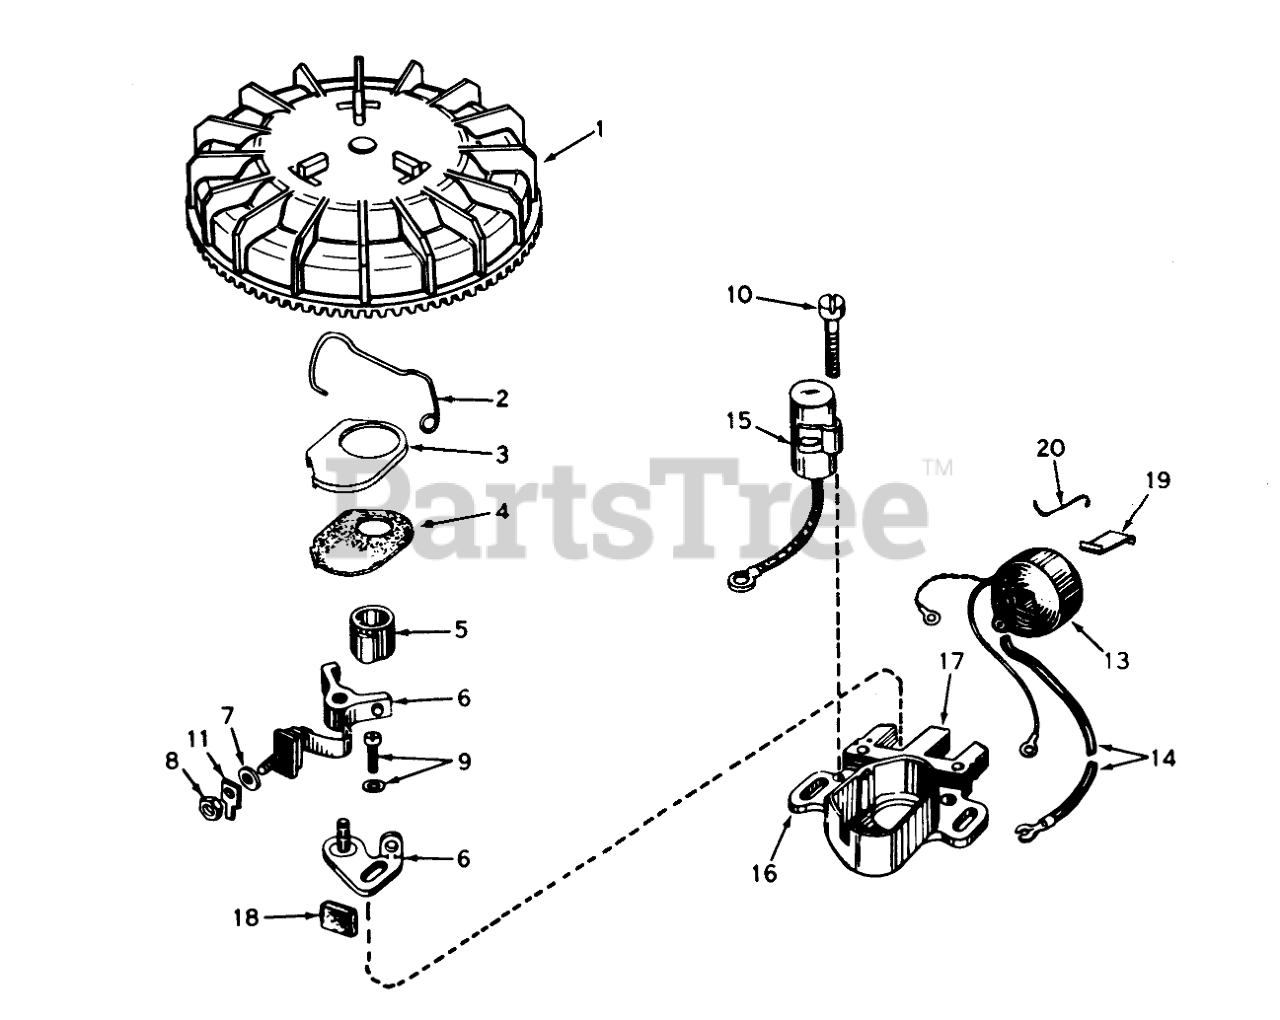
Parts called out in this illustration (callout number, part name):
1	Flywheel (Incl. Ref. #3 & 4)
2	Spring Breaker Box
3	Cover-Dust
4	Gasket, Dust Cover
5	Cam, Breaker
6	Breaker Assy.
9	Breaker Screw
10	Condenser Screw
11	Terminal, Ground
13	Coil Assembly (Incl. Ref. #14)
14	Wire, Lead
15	Condenser
16	Core & Plate
17	Stator Assembly (Incl. Ref. #2, 3, 4, 6 thru 16, 18, 19 & 20)
18	Felt,Cam Wiper
19	Spring Coil Wedge
20	Clip, Coil
